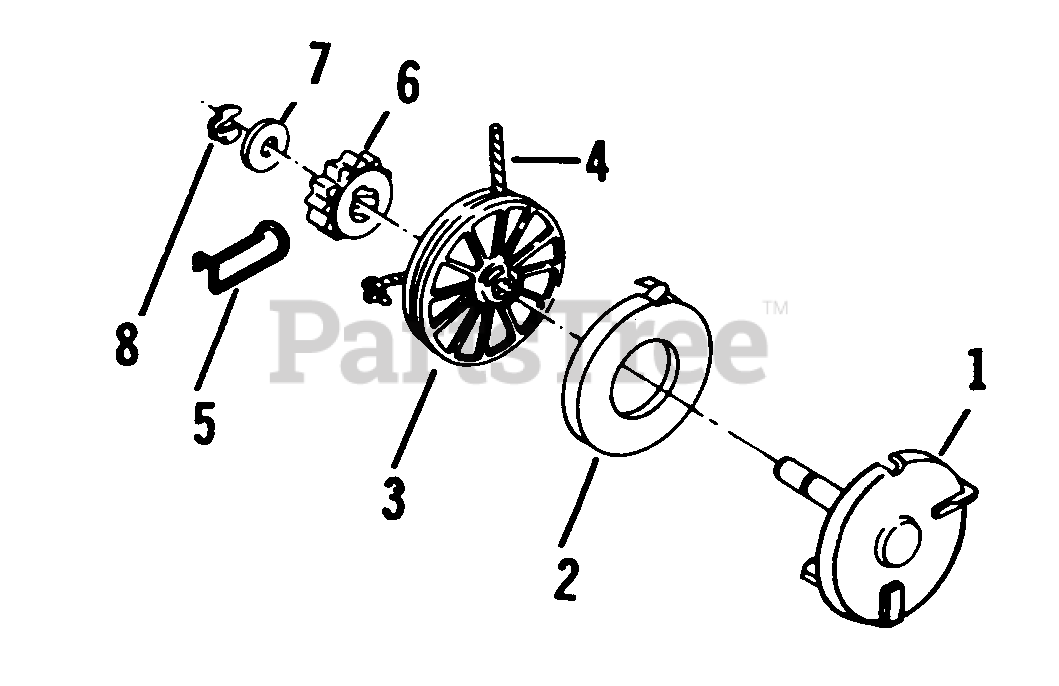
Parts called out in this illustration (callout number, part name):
1	Spring Cup and Pin Assembly
2	Spring and Retainer Assembly
3	Pulley
4	Rope
5	Spring-Drag
6	Pinion
7	Washer
8	Retainer
